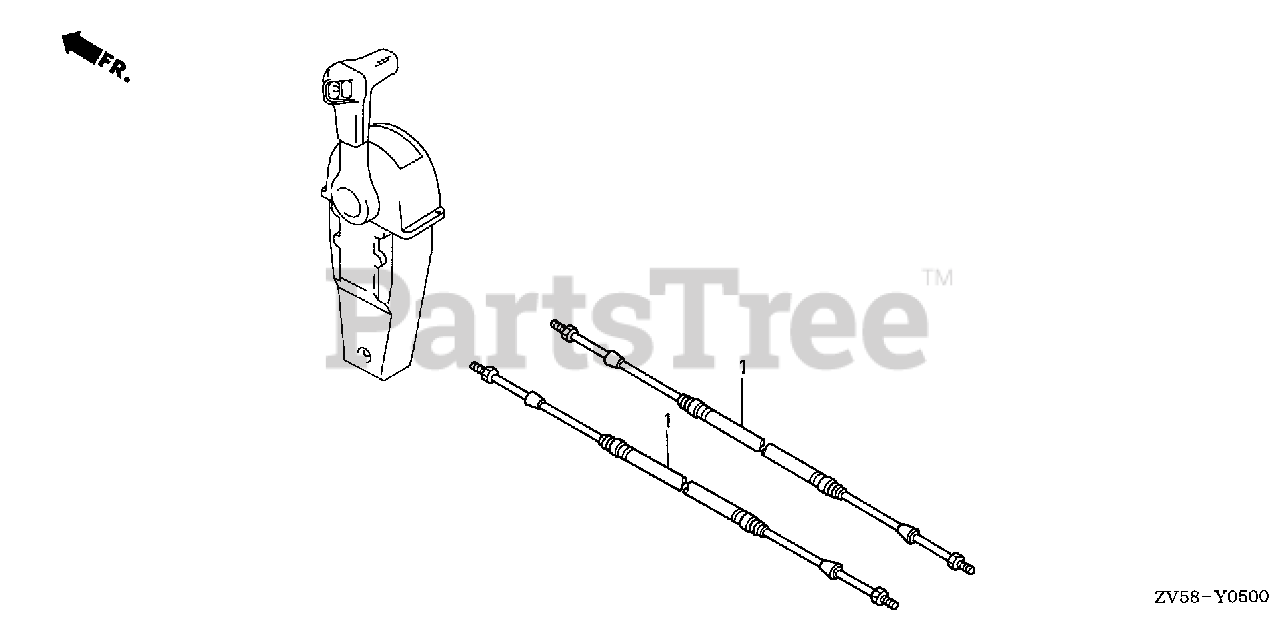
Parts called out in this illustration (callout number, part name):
1	CABLE ASSY., PUSH-PULL (33C-5FT)
1	CABLE ASSY., PUSH-PULL (33C-6FT)
1	CABLE ASSY., PUSH-PULL (33C-7FT)
1	CABLE ASSY., PUSH-PULL (33C-8FT)
1	CABLE ASSY., PUSH-PULL (33C-9F T)
1	CABLE ASSY., PUSH-PULL (33C-10FT)
1	CABLE ASSY., PUSH-PULL (33C-11FT)
1	CABLE ASSY., PUSH-PULL (33C-12 FT)
1	CABLE ASSY., PUSH-PULL (33C-13 FT)
1	CABLE ASSY., PUSH-PULL (33C-14FT)
1	CABLE ASSY., PUSH-PULL (33C-15 FT)
1	CABLE ASSY., PUSH-PULL (33C-16FT)
1	CABLE ASSY., PUSH-PULL (33C-17 FT)
1	CABLE ASSY., PUSH-PULL (33C-18 FT)
1	CABLE ASSY., PUSH-PULL (33C-19FT)
1	CABLE ASSY., PUSH-PULL (33C-20FT)
1	CABLE ASSY., PUSH-PULL (33C-21FT)
1	CABLE ASSY., PUSH-PULL (33C-22FT)
1	CABLE ASSY., PUSH-PULL (33C-23FT)
1	CABLE ASSY., PUSH-PULL (33C-24FT)
1	CABLE ASSY., PUSH-PULL (33C-25FT)
1	CABLE ASSY., PUSH-PULL (33C-26FT)
1	CABLE ASSY., PUSH-PULL (33C-27FT)
1	CABLE ASSY., PUSH-PULL (33C-28FT)
1	CABLE ASSY., PUSH-PULL (33C-29FT)
1	CABLE ASSY., PUSH-PULL (33C-30FT)
1	CABLE ASSY., PUSH-PULL (33C-31FT)
1	CABLE ASSY., PUSH-PULL (33C-32FT)
1	CABLE, REMOTE CONTROL (10'') (LOW FRICTION)
1	CABLE, REMOTE CONTROL (11'') (LOW FRICTION)
1	CABLE, REMOTE CONTROL (12'') (LOW FRICTION)
1	CABLE, REMOTE CONTROL (13'') (LOW FRICTION)
1	CABLE, REMOTE CONTROL (14'') (LOW FRICTION)
1	CABLE, REMOTE CONTROL (15'') (LOW FRICTION)
1	CABLE, REMOTE CONTROL (16'') (LOW FRICTION) (NOT AVAILABLE)
1	CABLE, REMOTE CONTROL (17'') (LOW FRICTION)
1	CABLE, REMOTE CONTROL (18') (LOW FRICTION) (NOT AVAILABLE)
1	CABLE, REMOTE CONTROL (1 9'') (LOW FRICTION)
1	CABLE, REMOTE CONTROL (20'') (LOW FRICTION) (NOT AVAILABLE)
1	CABLE, REMOTE CONTROL (21') (LOW FRICTION)
1	CABLE, REMOTE CONTROL (22') (LOW FRICTION) (NOT AVAILABLE)
1	CABLE, REMOTE CONTROL (2 3'') (LOW FRICTION)
1	CABLE, REMOTE CONTROL (24') (LOW FRICTION) (NOT AVAILABLE)
1	CABLE, REMOTE CONTROL (25') (LOW FRICTION)
1	CABLE, REMOTE CONTROL (26') (LOW FRICTION)
1	CABLE, REMOTE CONTROL (27') (LOW FRICTION)
1	CABLE, REMOTE CONTROL (28') (LOW FRICTION) (NOT AVAILABLE)
1	CABLE, REMOTE CONTROL (2 9') (LOW FRICTION)
1	CABLE, REMOTE CONTROL (30') (LOW FRICTION) (NOT AVAILABLE)
1	CABLE, REMOTE CONTROL (31') (LOW FRICTION)
1	CABLE, REMOTE CONTROL (32') (LOW FRICTION) (NOT AVAILABLE)
1	CABLE, REMOTE CONTROL (33') (LOW FRICTION)
1	CABLE, REMOTE CONTROL (34') (LOW FRICTION)
1	CABLE, REMOTE CONTROL (35') (LOW FRICTION)
